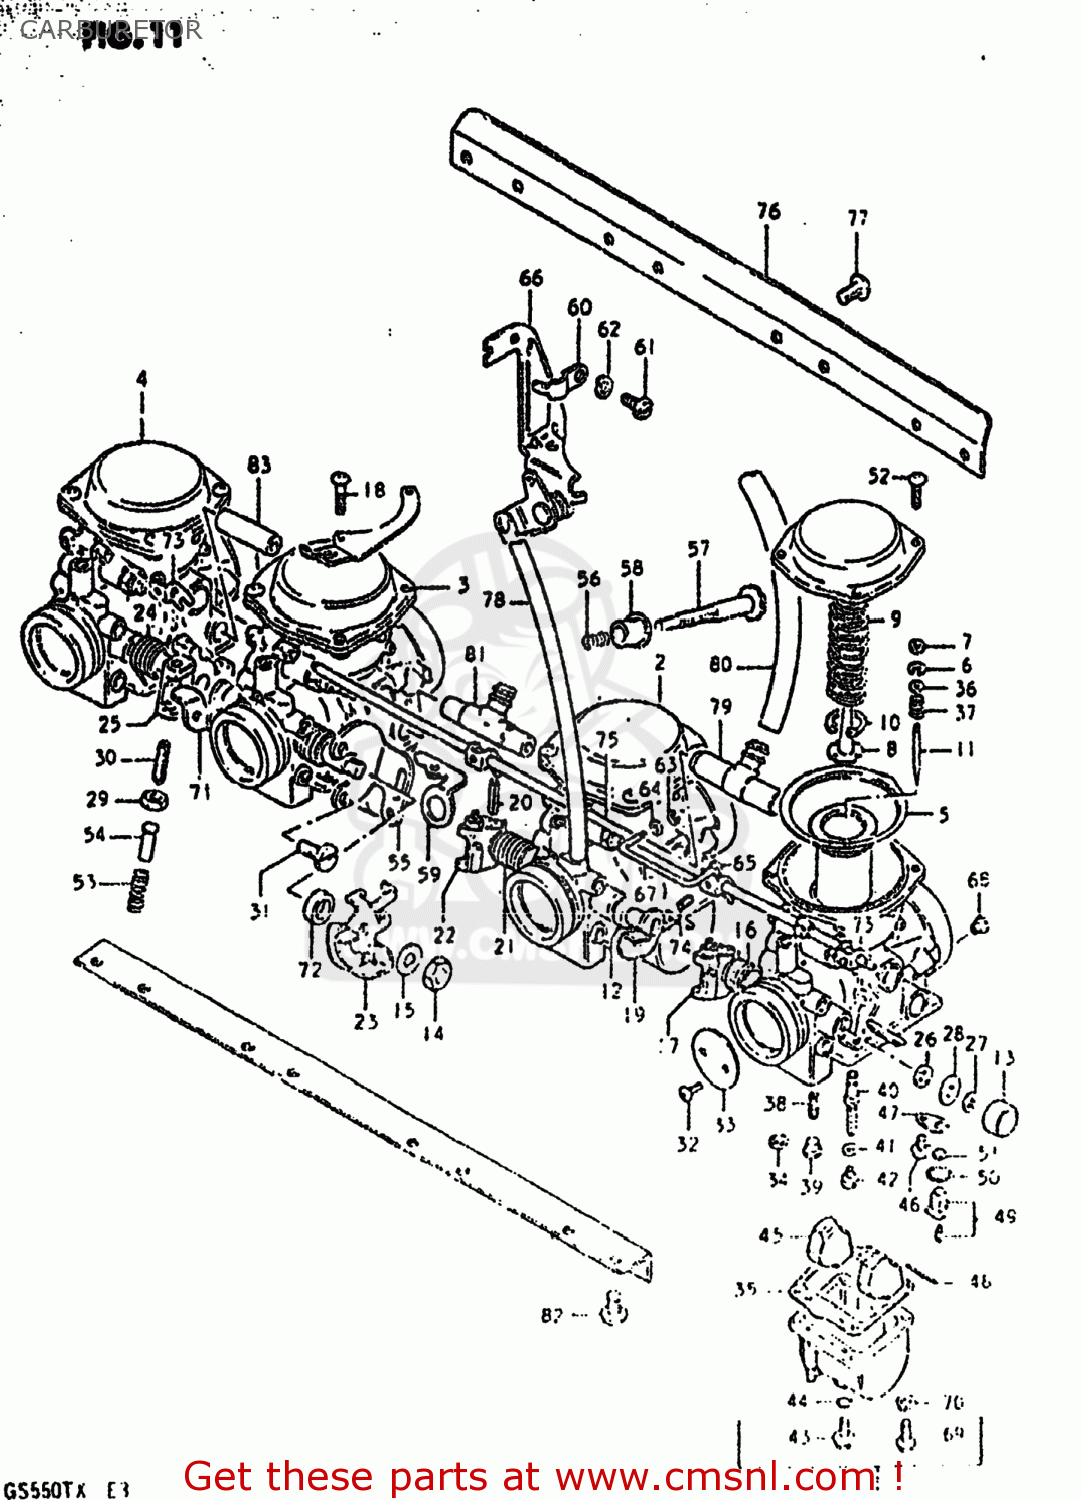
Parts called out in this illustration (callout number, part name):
1	CARBURETOR ASSEMBLY,NO.1 (A
2	CARBURETOR ASSEMBLY
3	CARBURETOR ASSEMBLY
4	CARBURETOR ASSEMBLY
5	DIAPHRAGM ASSEMBLY
6	CLIP,NEEDLE
7	RING
8	HOLDER,GUIDE
9	SPRING
10	E RING
11	NEEDLE JET
12	GASKET,THROTTLE SHAFT (NAS)
13	CAP
14	NUT
15	WASHER
16	SPRING,THROTTLE SHAFT
17	SHAFT,THROTTLE
18	SCREW
19	SHAFT,THROTTLE
20	PIN,THROTTLE SHAFT
21	SPRING,THROTTLE SHAFT
22	LEVER,THROTTLE SHAFT
23	LEVER ASSEMBLY,THROTTLE
24	SPRING,THROTTLE SHAFT
25	SHAFT,THROTTLE
26	SEAL
27	E RING
28	GASKET,THROTTLE SHAFT (NAS)
29	NUT
30	SCREW
31	SCREW,THROTTLE ADJUST B
32	SCREW
33	VALVE,THROTTLE
34	GASKET (NAS)
35	GASKET,FLOAT CHAMBER (NAS)
36	WASHER
37	SPRING
38	JET,PILOT
39	PLUG,NEEDLE JET
40	JET,NEEDLE
41	WASHER,NEEDLE NOZZLE
42	JET,MAIN(92.5)
43	PLUG,DRAIN
44	GASKET (NAS)
45	FLOAT
46	SCREW
47	PLATE
48	PIN,FLOAT
49	VALVE ASSEMBLY,NEEDLE
50	O-RING,NEEDLE VALVE
51	FILTER
52	SCREW
53	SPRING,THROTTLE SCREW
54	PIN,THROTTLE LEVER
55	BRACKET,THROTTLE ADJUST
56	SPRING
57	SCREW
58	BUSH
59	BRACKET,THROTTLE ADJUST
60	BRACKET,STARTER
61	BOLT
62	LOCK WASHER
63	CAP,LEVER
64	SEAT,SPRING
65	LEVER ASSY
66	BRACKET
67	ROD,STARTER LEVER
68	JET,AIR(150)
69	SCREW
70	LOCK WASHER
71	SHAFT,THROTTLE
72	WASHER
73	LEVER
74	SCREW
75	SHAFT,STARTER
76	BRACKET
77	SCREW
78	HOSE
79	NIPPLE
80	HOSE
81	NIPPLE,CARBURETOR
82	SCREW 6X12
83	NIPPLE
